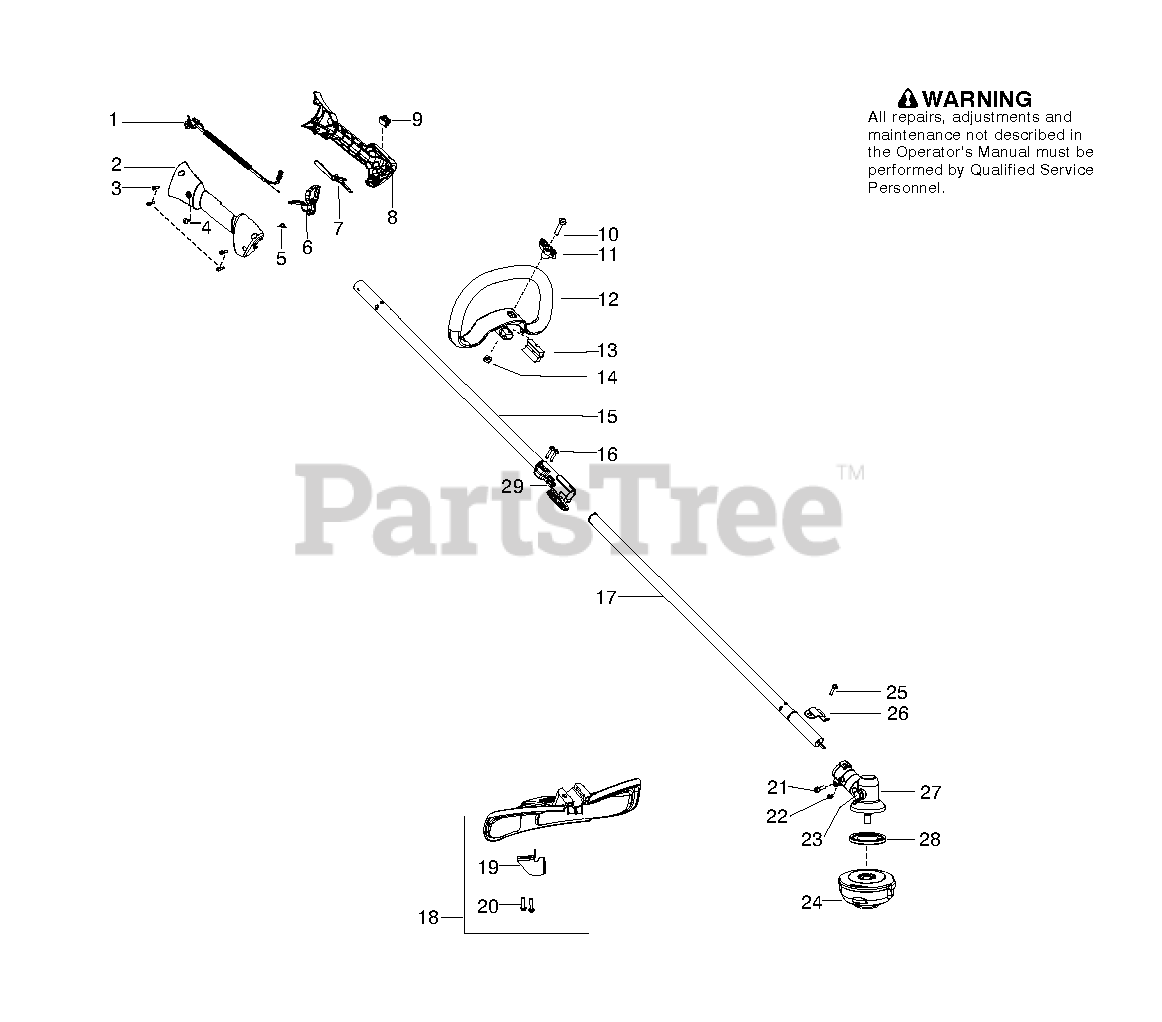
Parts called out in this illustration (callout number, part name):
1	ASSY CABLE / WIRE HARNESS
2	HSG THROTTLE RIGHT HVA
3	SCREW M4 X 1.75 PT 16MM
4	SCREW-10-14 X 1/2 PLASTITE
5	SPRING TRIGGER
6	TRIGGER THROTTLE HVA ORANGE
7	THROTTLE LOCKOUT HVA ORANGE
8	HSG THROTTLE LEFT HVA
9	SWITCH
10	SCREW M6X50
12	ASSY LOOP HANDLE
13	SPACER PLASTIC
15	DRIVE SHAFT
17	KIT DRIVESHAFT LOWER LDX
18	KIT COBI SHIELD
19	Limiter - Line
21	SCREW - CARB. ADAPTOR
23	PLUG GREASE 9MM
24	T25 TRIM HEAD 10MM LH
25	SCREW 1/4-20 X 7/8 (TAP
26	BRACKET SHIELD STRAIGHT SHAFT
27	ASSY GEARBOX
28	DRIVE DISC
29	CLAMPING SLEEVE
